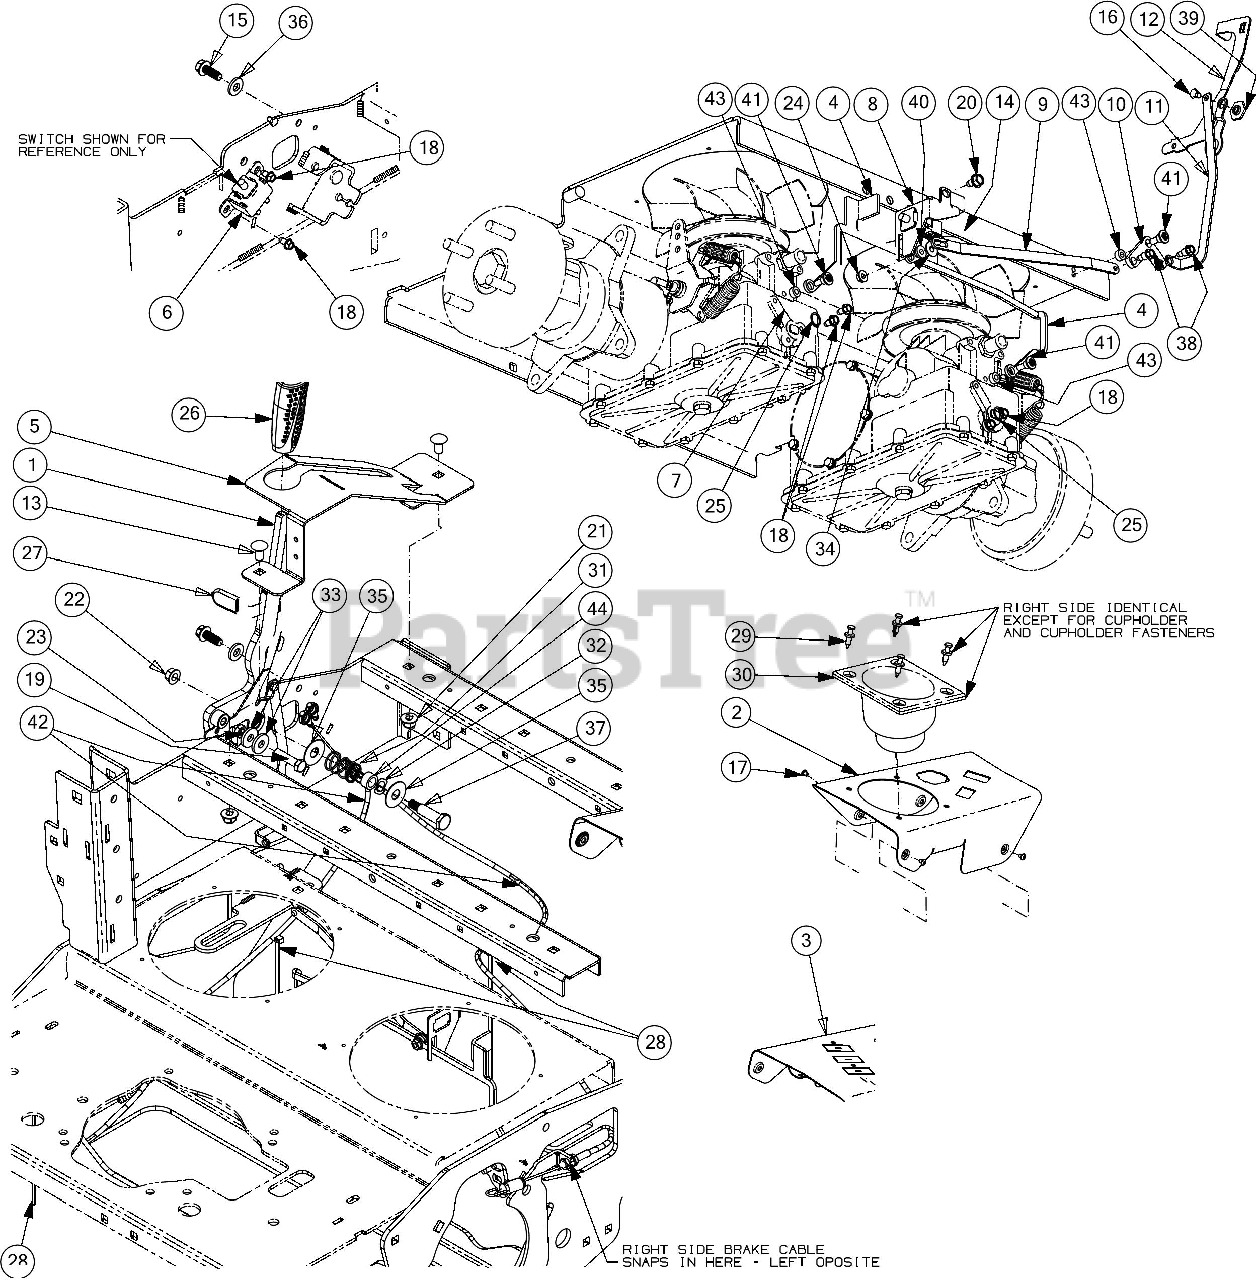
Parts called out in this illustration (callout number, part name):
1	BRAKE HANDLE ASSEMBLY
2	CONTROL PANEL (LH)
3	CONTROL PANEL (RH)
4	DUMP VALVE BRACKET
5	BRAKE BOOT BRACKET
6	BRAKE PANEL MOUNT
7	TRANSMISSION BYPASS LEVER
8	NEUTRAL BRACKET
9	ACTUATOR ARM LINK
10	NEUTRAL CONTROL LEVER
11	NEUTRAL ARM LINK
12	RELEASE VALVE LEVER
13	CARRIAGE BOLT 3/8-16 X .750 GR5
14	SCREW 1/4-20 X .75 GR5
15	SCREW 3/8-16 X 1
16	SCREW M6 X 8MM
17	SCREW #10-32 X .25
18	SCREW 1/4-20 X.500
19	SCREW 3/8-16 X 1.50 GR8
20	SCREW 5/16-18 x .500
22	HEX LOCK NUT
24	LOCK NUT 1/4
25	SNAP RING
27	SEAT ADJUSTER GRIP
28	7" CABLE TIE
29	PLASTIC RIVET
30	CUP HOLDER
31	COMPRESSION SPRING .844X.970X1.50
32	WAVE WASHER
33	FLAT WASHER .385 X 1.00 X .135
34	FLAT WASHER .283 ID X .749 X .030
35	FLAT WASHER
36	FLAT WASHER
37	SHOULDER SCREW .498 DIA X 1.450-THD
38	SHOULDER SCREW
39	SHOULDER SPACER
40	SHOULDER SPACER
41	SHOULDER SCREW .375X.280:1/4-14
42	BRAKE CABLE
